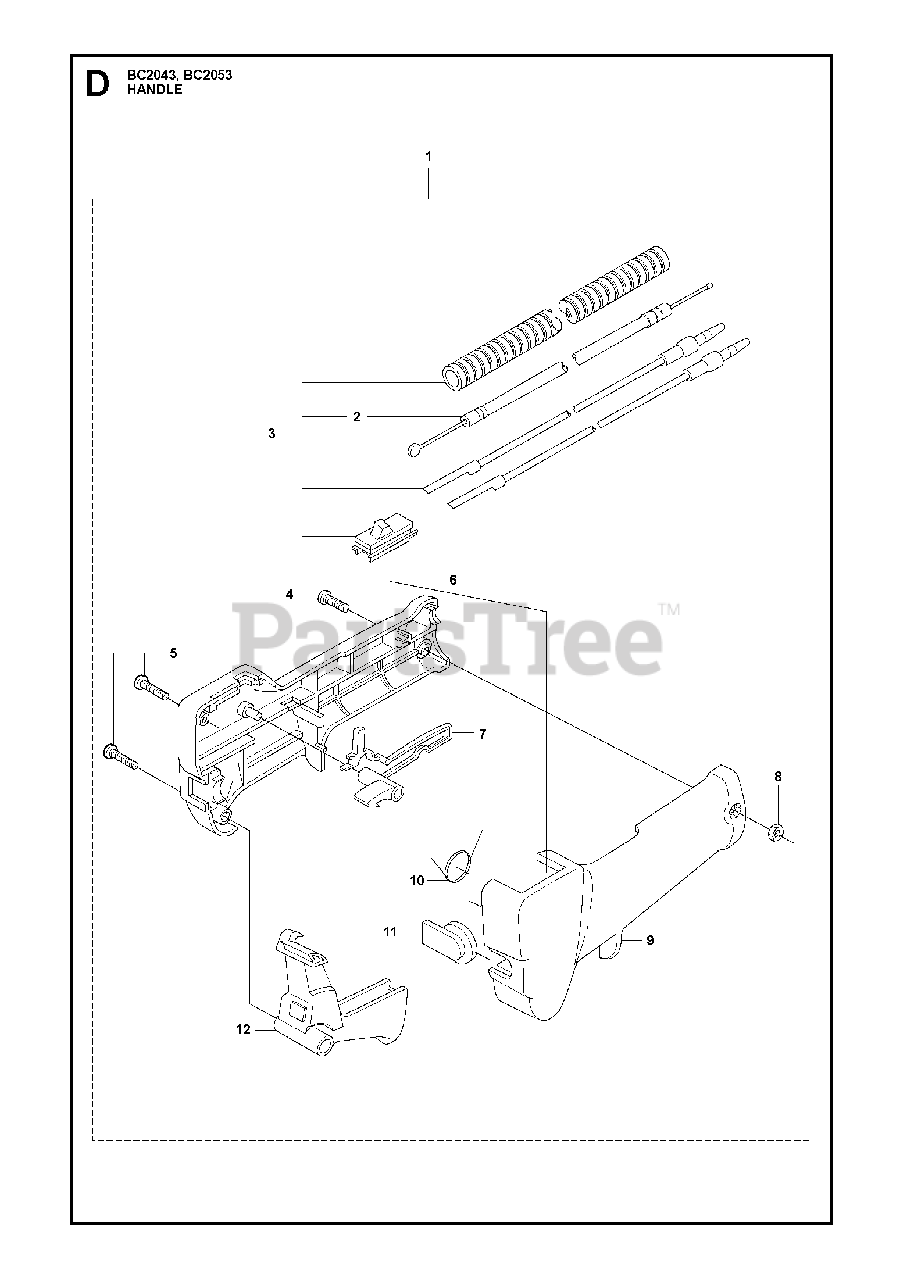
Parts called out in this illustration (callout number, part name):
4	SCREW
8	NUT M6M M5
12	LEVER
